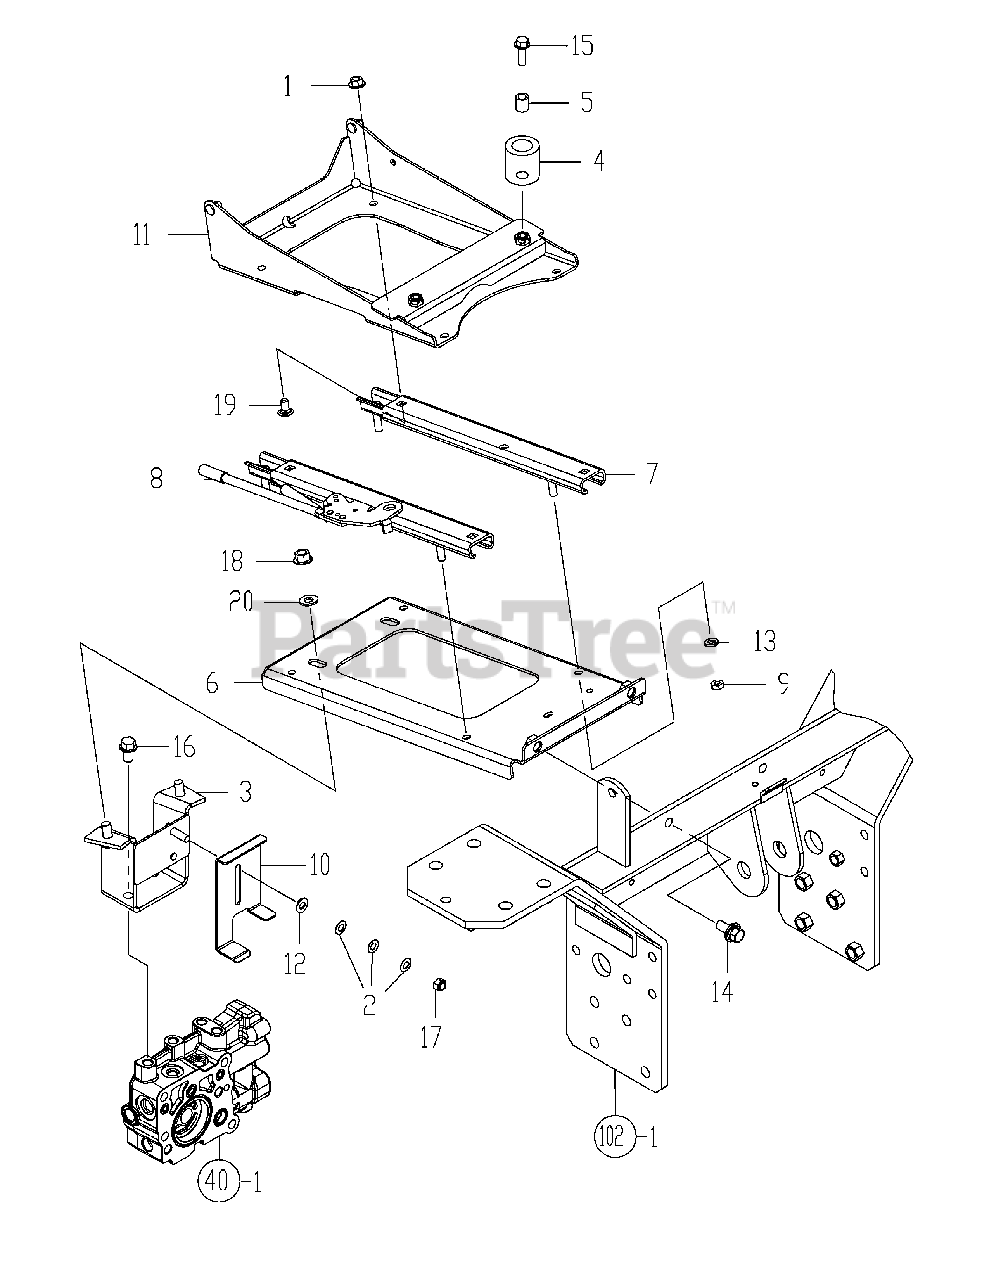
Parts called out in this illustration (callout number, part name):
3	STAY (SEAT CMP)
6	STAY CMP, RAIL A
7	RAIL CMP, SEAT
8	RAIL CMP, SEAT LEVER
9	UNC NUT 5/16-18
11	STAY CMP, RAIL B
